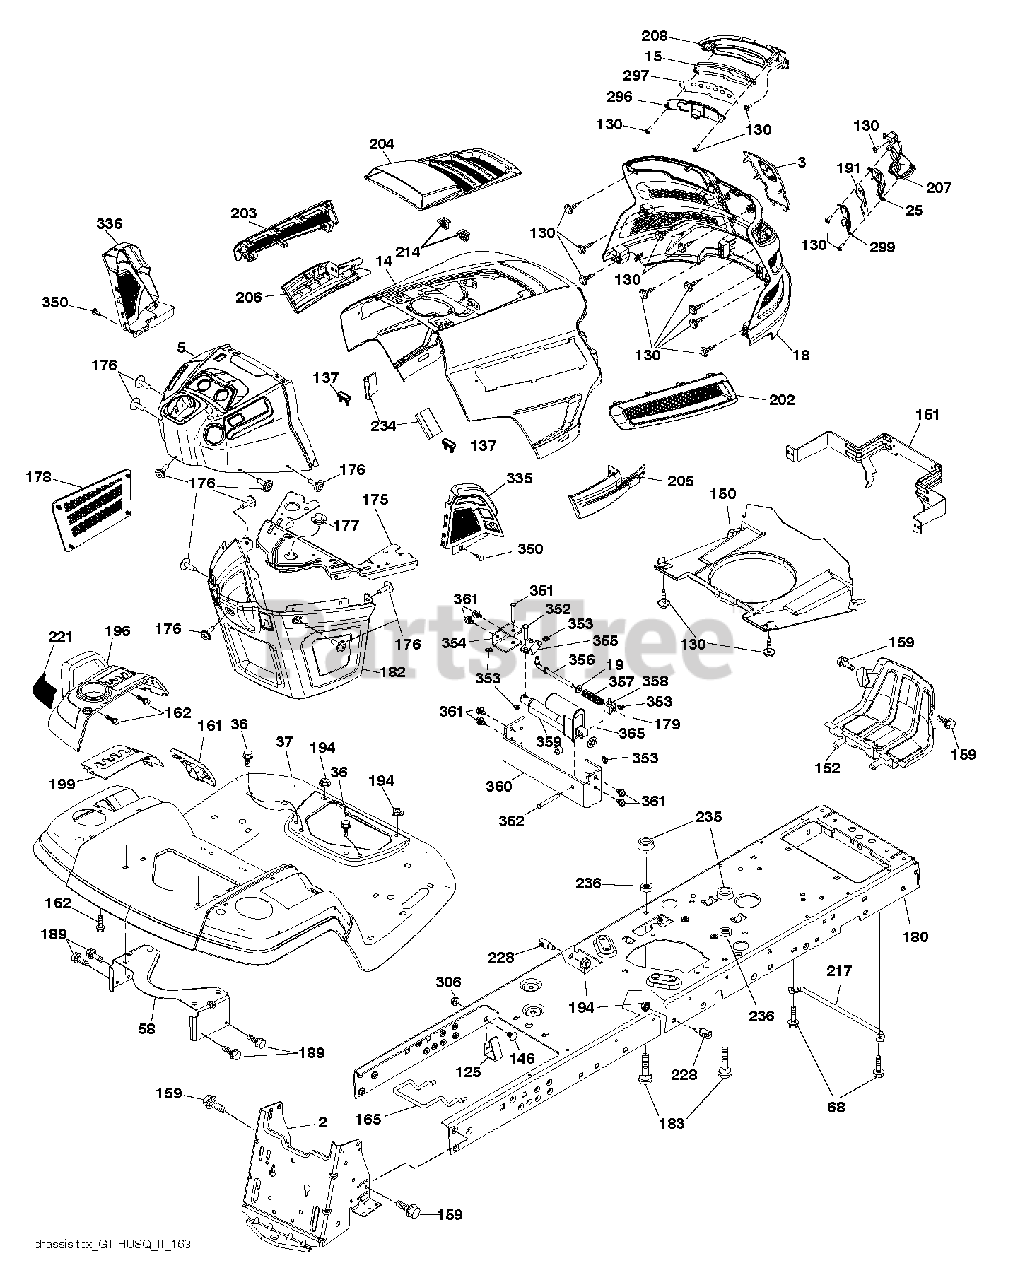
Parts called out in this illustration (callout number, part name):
2	DRAWBAR.STGT
3	APPLIQUE.SUBASM.GT.HUSQ.II
5	GT2.DASH.UPPER.W/BUMPER
14	HOOD.ASM.HUSQVARNA.GT.TEX.ORAN
15	LED LIGHT.LH
18	GRILLE.SUBSTRATE.2011.
19	WASHER
25	LENS.RH
36	SCREW 5/16"
37	FENDER.PNT.TX.GT.CH/FW/DL.HUSQ
58	BRKT.SUPPORT.FNDR/TANK
68	SCREW LT
125	CLIP.FUEL.LINE
130	SCREW.#10 X 0.750.BOS
137	BUMPER DASH
146	BOLT.RDHD.SHT.SQNK.3/8-16X5/8
150	AIR.DUCT.GTV.BLACK
151	BRACKET.PIVOT.HOOD.GT.HUSQ.II
152	SHIELD.BROWNING.PNT.GT.V2
159	SCREW, 3/8-16X3/4
161	CONSOLE.WINDOW.FUEL.HUSQ.GT
162	SCREW.HI-LO.CONSOLE
165	SUPPORT.TANK.REAR.B/TE
175	PLATE.CROSSMEMBER.HUSQ
176	SCREW.#10-24X5/8.RN.QU
177	BUSHING, STEERING
178	CARGO.ASM.NET.TXGT.W/C
180	CHASSIS.TEX.BOLTED
182	DASH.LOWER.COMMON.12V.ADAPTOR
183	BOLT.5/16-18X1-1/4 FULL THD
189	SCREW
191	INSERT INFLECT.RH
194	NUT LOCK HEX FLANGE 5/16-18
196	CONSOLE.ASM.DECKLIFT.HUSQGT.DL
199	PLATE.DECK.LIFT.HUSQVARNA.GT
202	VENT.SIDE.RH.GT.HUSQ.II.
203	VENT.SIDE.LH.GT.HUSQ.II.498
204	VENT.TOP.HUSQ.GT2
205	SIDE.TRIM.RH.GT.HUSQ.II
206	SIDE.TRIM.LH.GT.HUSQ.II.GRAY
207	LIGHT.BEZEL. RH
208	LIGHT.BEZEL.LH
214	CLIP.RETAINER.TINNER.
217	ROD.PIVOT.HOOD
221	REFLECTOR.LH.TEX GT HU
228	STUD.FASTNER.W/ANTI-ROTATE
234	BUMPER.HOOD.TEX.HUSQVARNA
235	SPACER FENDER
236	NUT.CENTERLOCK.5/16-
296	LED LIGHT.LH
297	INSERT REFECT LH
299	LED LIGHT.RH
306	NUT LOCK FLG 3/8-16 UNC
335	COVER.LOWER.DASH.RH.BLACK
336	COVER-LH.LOWER.DASH.GT2.BLACK
350	CLIP.X-MAS.TREE
351	PIN.CLEVIS.375X2.125
352	PIN.CLEVIS.(.375 X 1.25)
353	CLIP RETAINER
354	SUPPORT.BELLCRANK
355	BELLCRANK.PIVOT.LOCK.DIFF
356	LINK.LOCK.DIFF
357	SPRING.COMPRESSION
358	GUIDE.SWIVEL
359	ACTUATOR.ELECTRIC
360	BRACKET.ACUATOR
361	SCREW LT.3/8-46X5/8
362	PIN.CLEVIS.(.375 X 2.42)
365	SPACER.NYLON.75" X .4375
